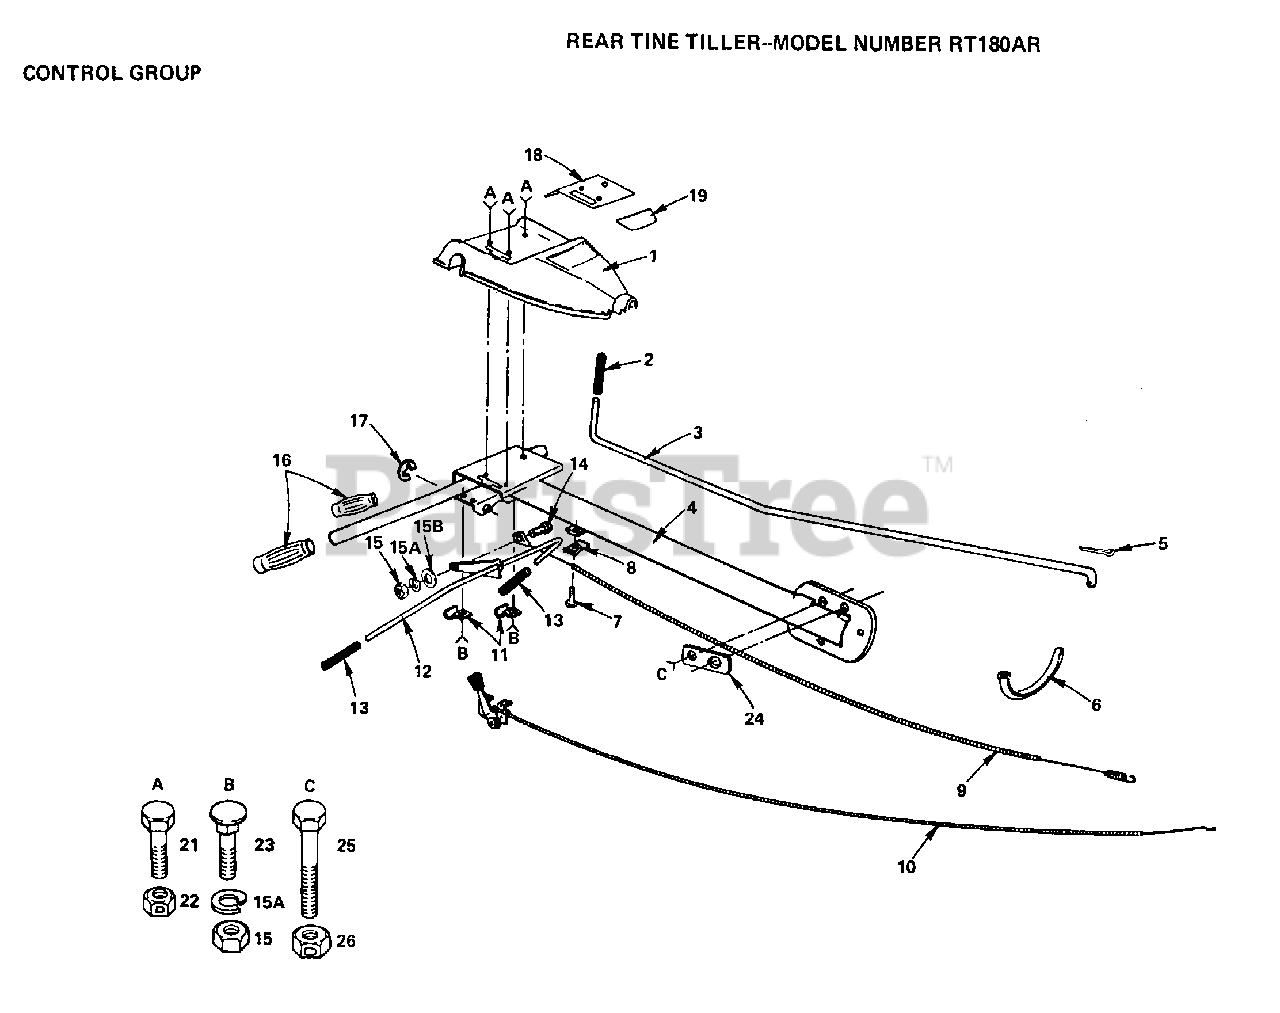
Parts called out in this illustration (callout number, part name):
1	PANEL - CONTROL
2	GRIP TI
4	ASSY-HANDLE TI
5	COTTER PIN
6	TIE CABLE CRT
7	SCREW TI
8	CONDIUT CLIP T
9	CABLE-CLUTCH TI
13	GRIP BAR CRT
14	SHOULDER BOLT ST
15A	LOCKWASHER
15B	WASHER
17	KLIP RING
18	DECAL - INSTRUCTION
19	DECAL - CONTROL PANEL
23	BOLT
24	"NUT, LOCK CRT"
25	BOLT
26	LOCKNUT
